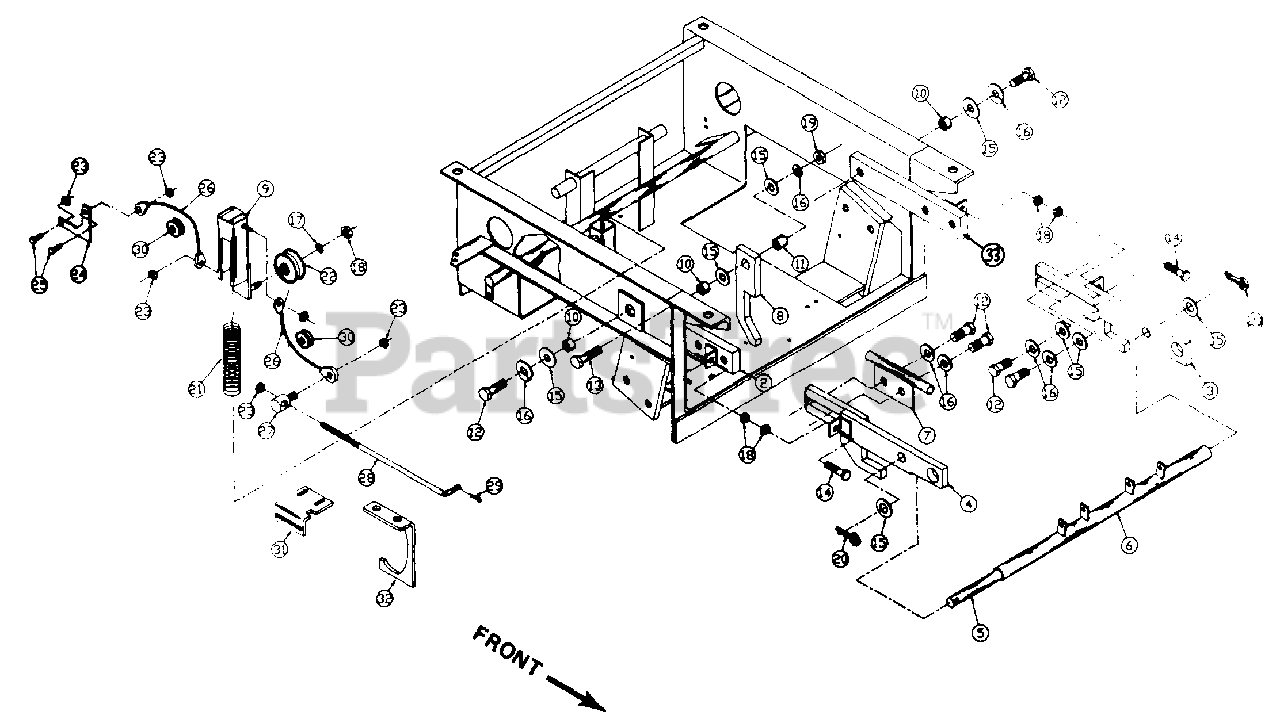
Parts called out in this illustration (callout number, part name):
2	Deck Arm
3	Deck Arm, Front, LH
4	Deck Arm, Front, RH
5	Cross Bar Pin
8	Forward Nose Down Lock
9	Drive Idler Tube
10	Deck Lift Arm Bushing, Short
11	Deck Lift Arm Bushing
12	Hex Bolt, 1/2-13 x 1 1/4", GR5
13	Hex Bolt, 1/2-13 x 2 1/4", GR5
14	Hex Tap Bolt, 3/8-16 x 3", GR5
15	Flatwasher, 1/2"
16	Lockwasher, 1/2"
17	Lockwasher, 3/8"
18	Hex Nut, 3/8-16
19	Hex Nut, 1/2-13
20	Cotter Pin, 1/8" x 1"
21	Trans. Belt Tightener Spring
22	Idler Pulley, 2 1/4" OD
23	Elastic Stop Nut, 1/4-20
24	L Brake Linkage
25	Hex Bolt, 1/4-20 x 1", GR5
26	Clutch Brake Cable
27	Caliper Rod Collar
29	Cotter Pin, 3/32" x 1"
30	Cable Pulley, 1 1/2" OD
31	Engine Belt Retainer Bracket
32	Engine Belt Retainer
33	Deck Arm, LH
